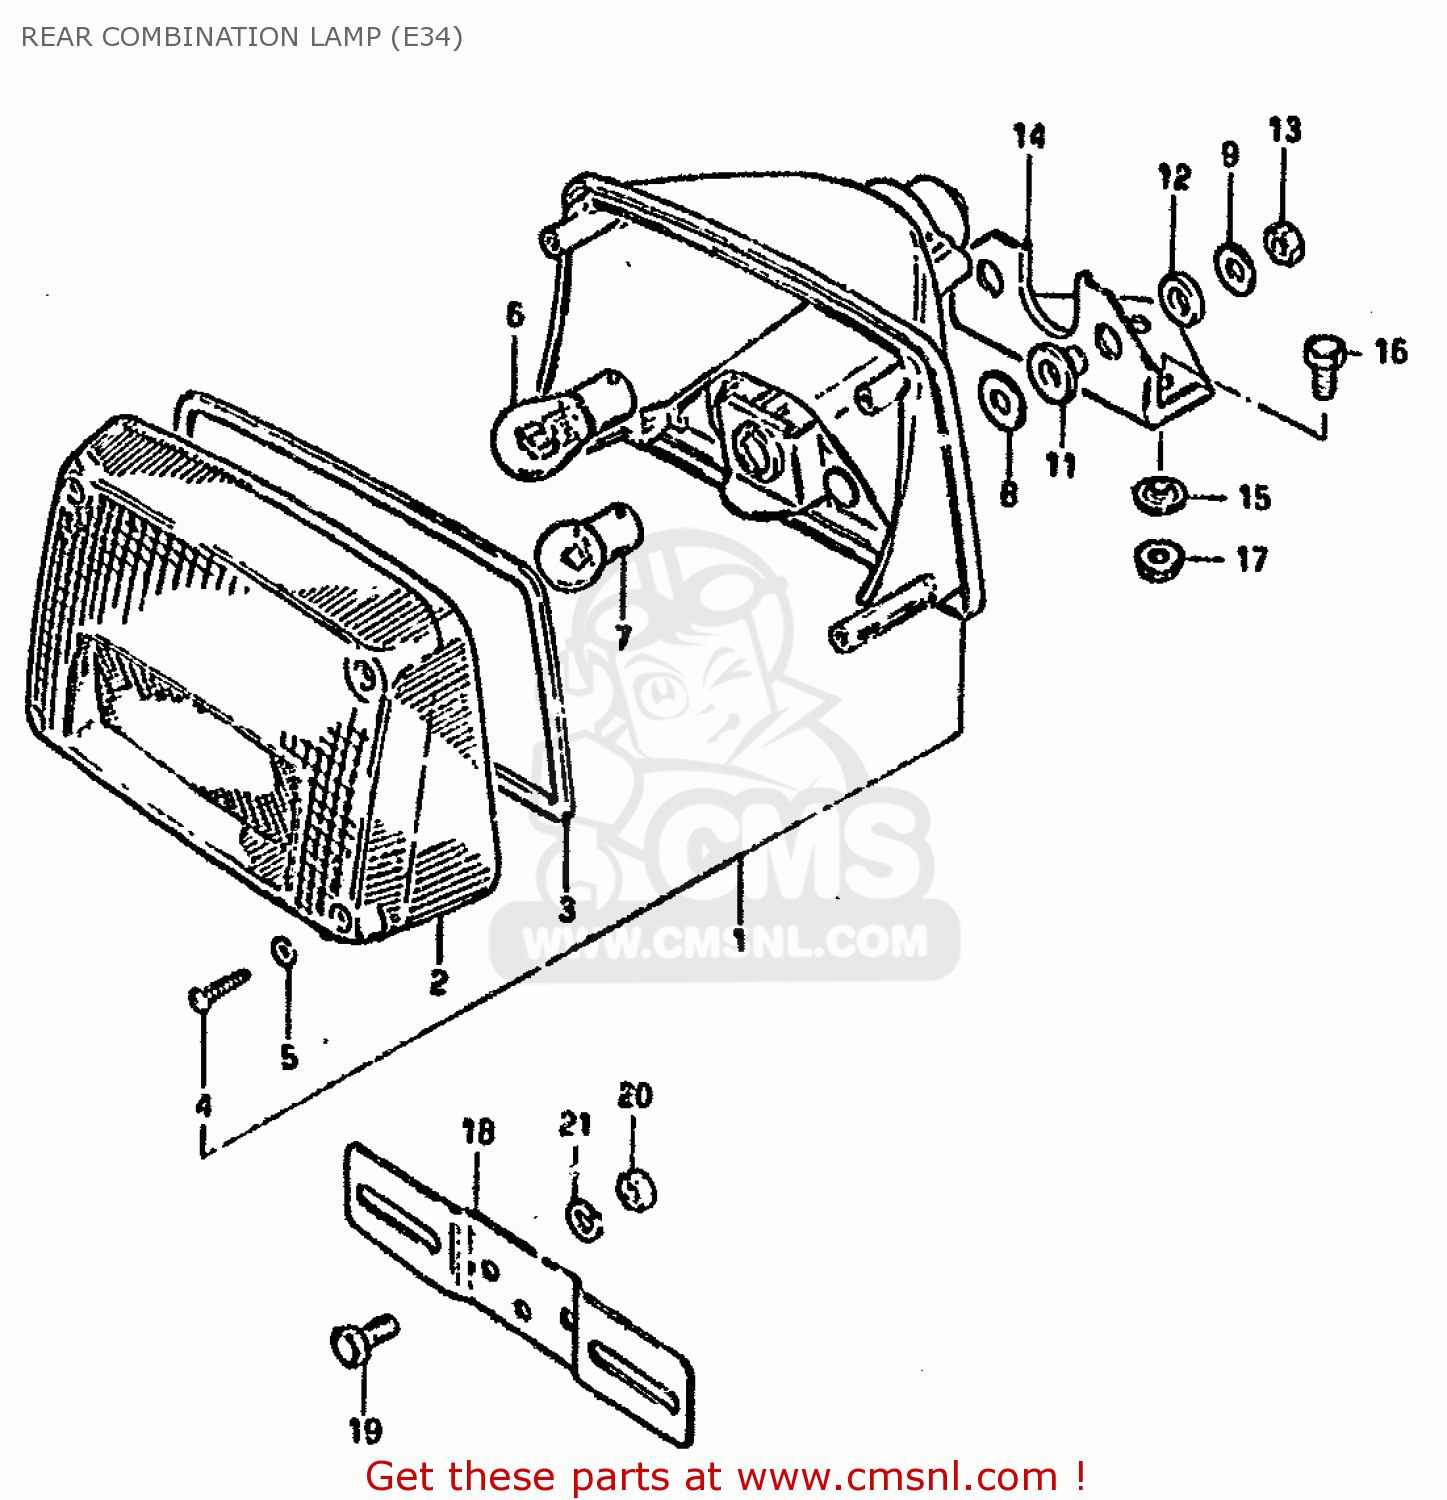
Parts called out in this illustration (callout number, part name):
1	LAMP ASSY, TAIL
2	LENS
3	GASKET (NAS)
4	SCREW,REAR COMBINATION LAMP
5	GASKET (NAS)
6	BULB(12V21/5W)
7	BULB
8	WASHER
9	WASHER(6,5X22X1.6)
10	SPACER(6.1X9X7.5)
11	CUSHION
12	CUSHION
13	NUT 6MM
14	BRACKET,RR COMBINATION LAMP
15	WASHER
16	BOLT, UPPER
17	NUT 6MM
18	PLATE,RR LICENSE
19	BOLT
20	NUT
21	LOCK WASHER
